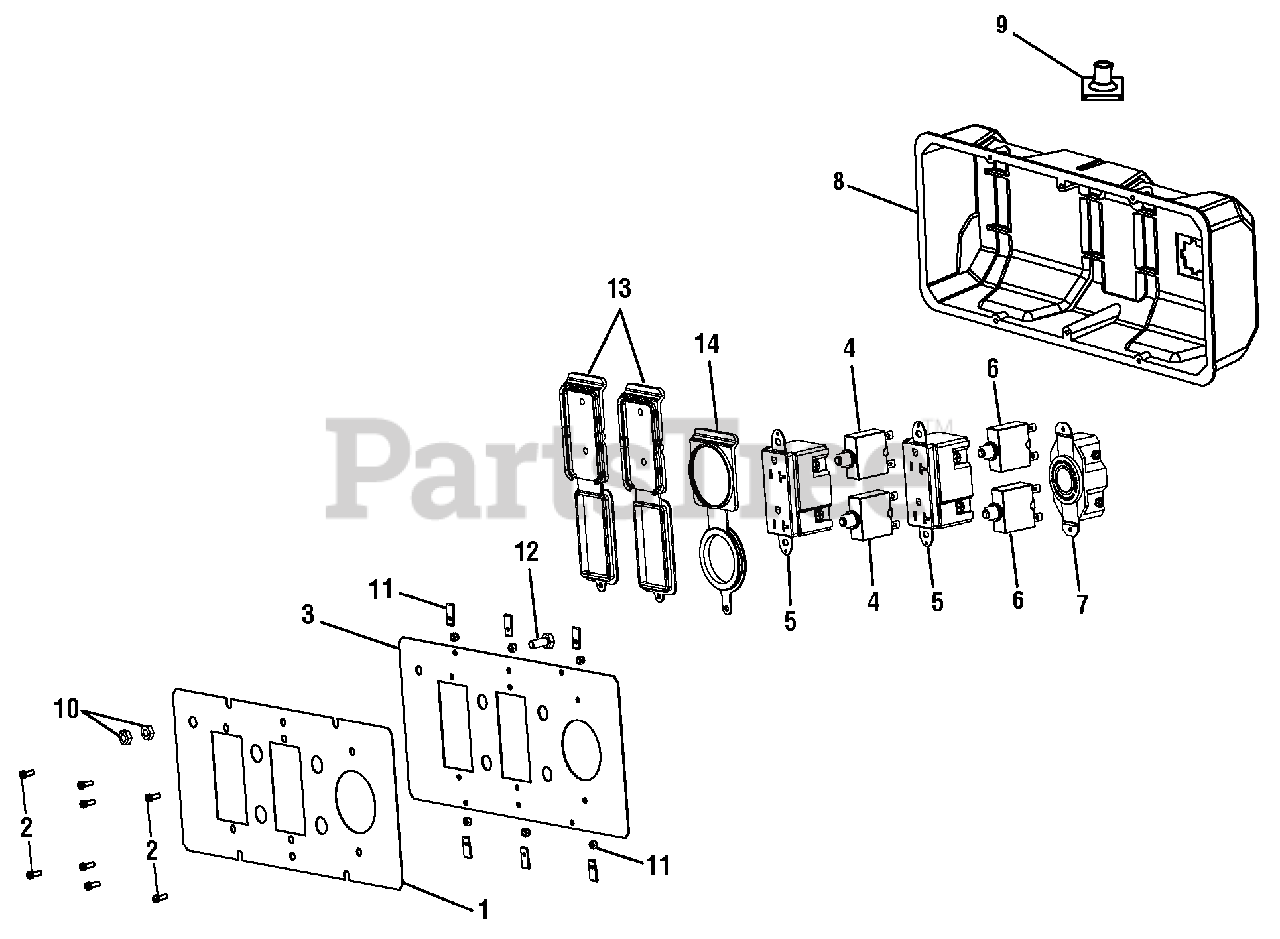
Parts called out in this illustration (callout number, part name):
1	Label (Power Outlet)
2	Screw (6-20 x 3/8 in.)
3	Front Panel
4	Circuit Breaker (20 Amp, 125 Volt)
5	120 Volt Duplex Receptacle
6	Circuit Breaker (30 Amp)
7	Twist Lock Receptacle (120/240 Volt, 30 Amp, L14-30R)
8	Control Box (Back Panel)
9	Rubber Boot (Control Panel Assembly)
12	Bolt (1/4-20 x .675 in.)
13	120 Volt Outlet Covers
14	240 Volt Outlet Covers
